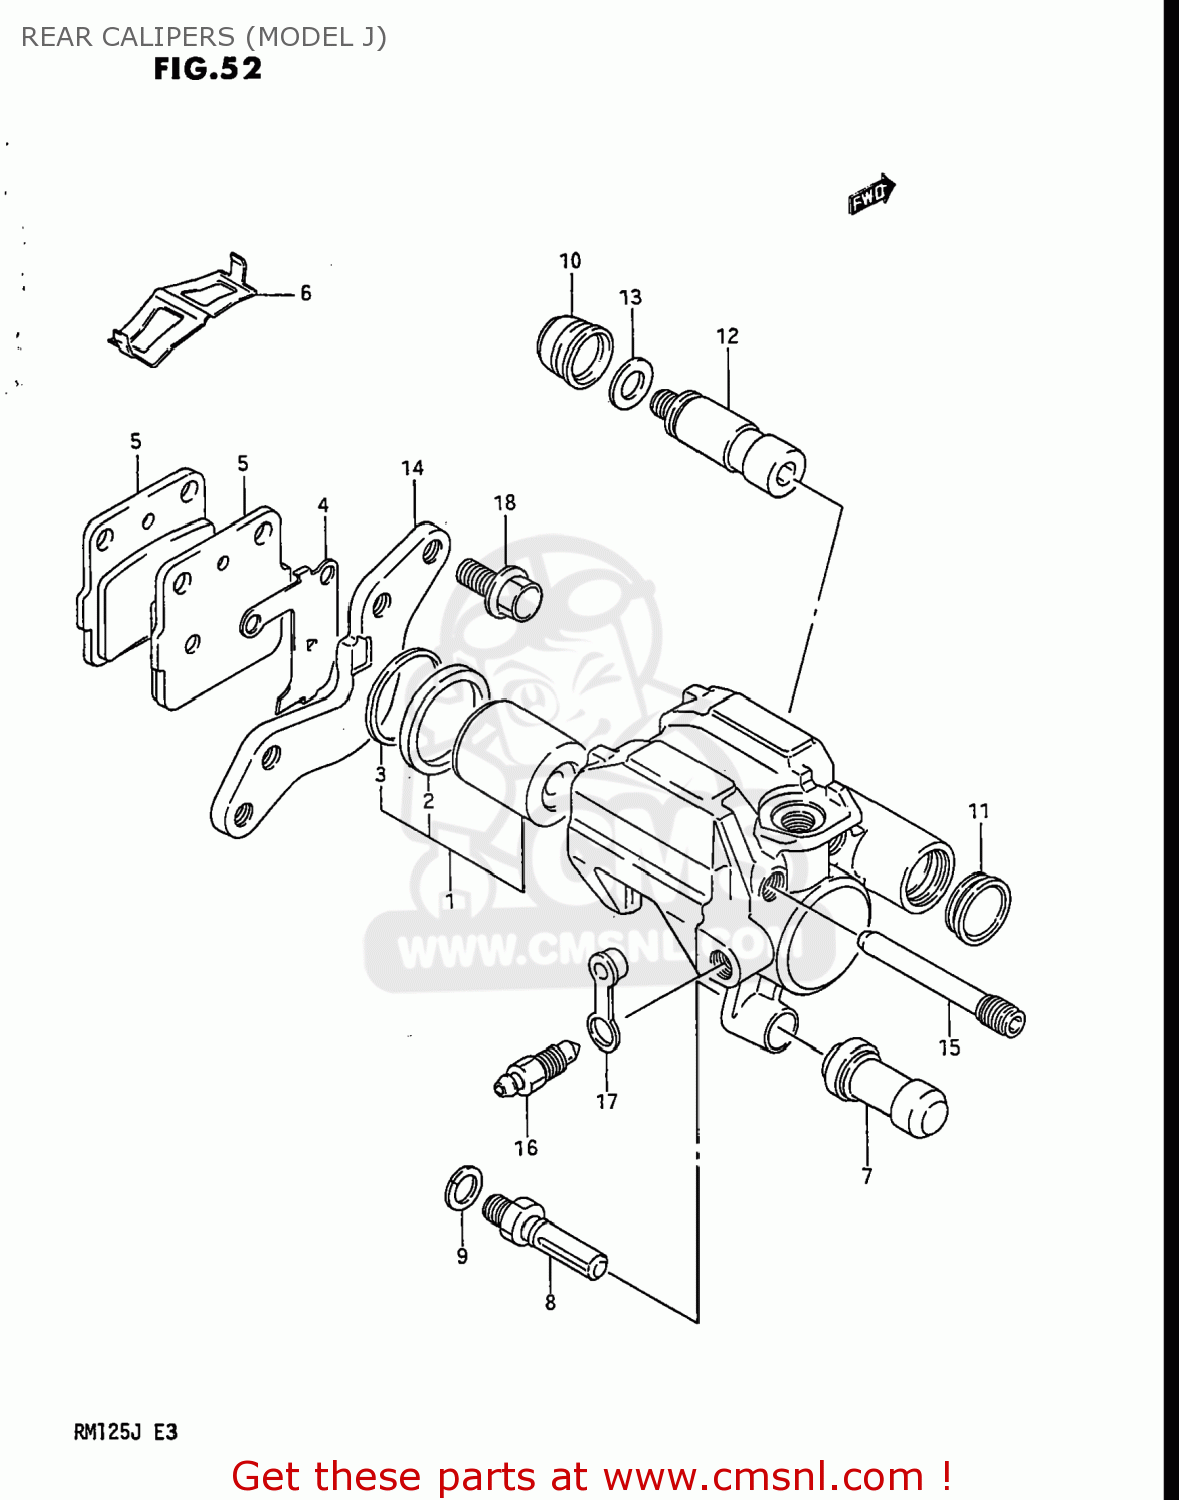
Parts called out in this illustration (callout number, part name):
1	PISTON SET
2	SEAL,PISTON
3	SEAL,DUST
4	SHIM
5	PAD (NAS)
6	SPRING,PAD
7	BOOT
8	BOLT,PIN
9	WASHER,WAVE
10	BOOT,PIN
11	DUST SEAL
12	PIN,SLIDE
13	SPRING,FRICTION
14	BRACKET
15	PIN
16	BLEEDER
17	CAP,BLEEDER
18	BOLT L:21
